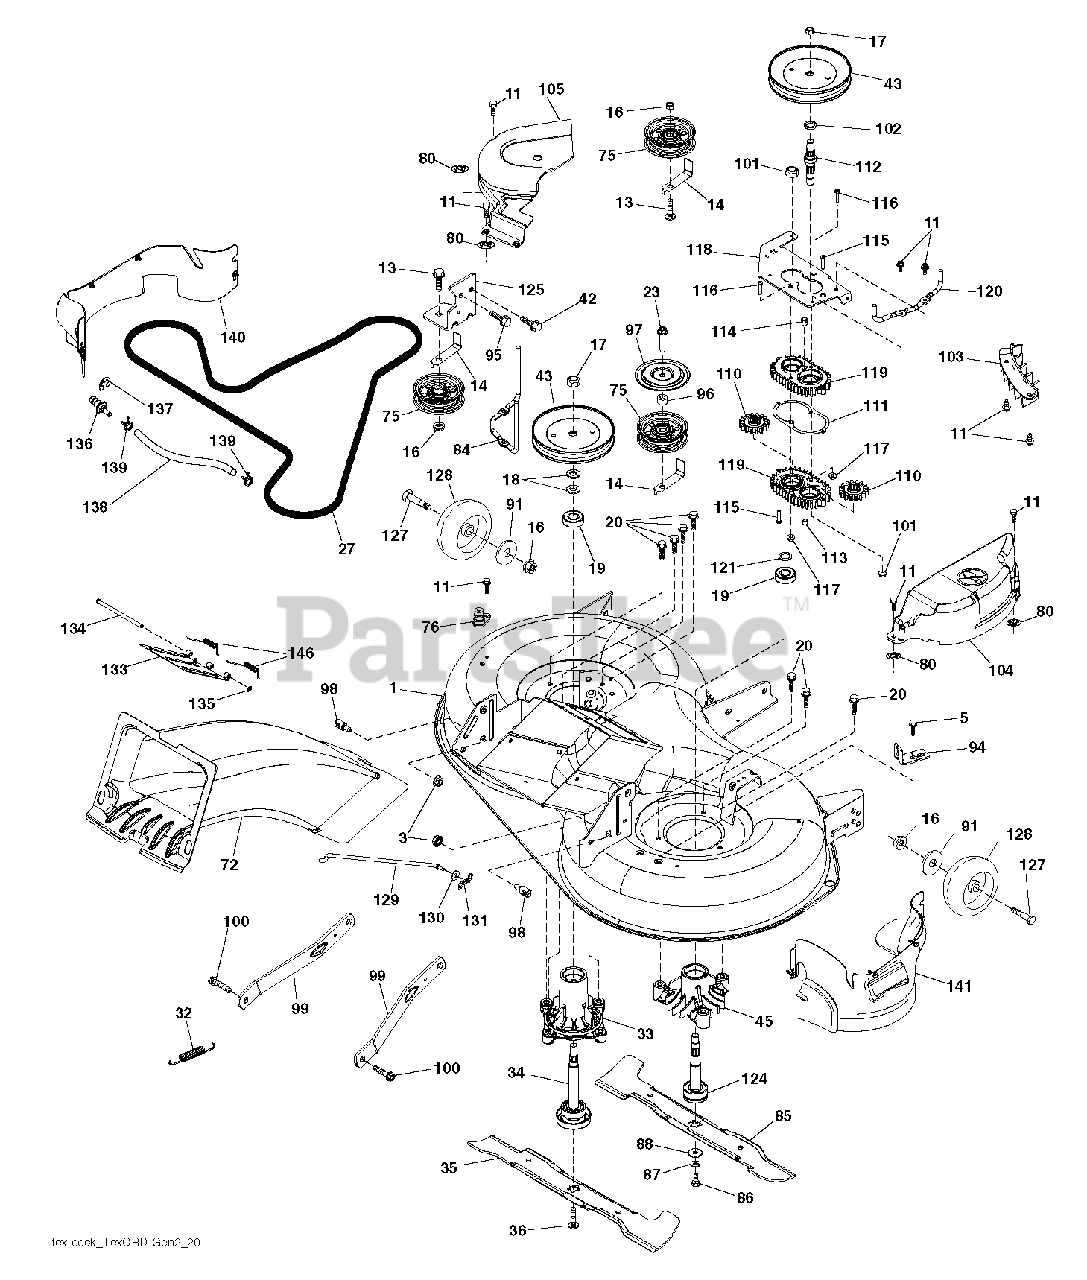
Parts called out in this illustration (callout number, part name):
3	NUT LOCK HEX FLANGE 5/16-18
5	BOLT.5/16HEX.WHS.HD
11	SCREW.1/4-20X5/8
13	BOLT.3/8-16X1.50
14	KEEPER, BELT IDLER
16	NUT LOCK FLG 3/8-16 UNC
17	NUT.FLANGE.LOCK.TOP
18	WASHER.SPACER.MANDREL
20	SCREW, WASHER HEAD
23	SCREW LT
27	BELT 97CM ELECTRIC
32	SPRING 107CM & 97CM ELECTRIC D
33	HOUSING.MANDREL.4PT.
34	SHAFT.ASM.MDRL.N/GREASE.38
35	BLADE.3N1.LH.CRD.97
36	BOLT.WASHER.ASM.7/16-2
42	SCREW
43	PULLEY.MANDREL.5.0.PD.38"
45	HOUSING.MANDREL.44/46" VENT
72	CHUTE.107/97.TEX.GEN2.TRIMMED
75	FLAT IDLER PULLEY
76	1/2" BARB.DECK.WASHOUT.PORT
80	PALNUT 1/4
84	BELT KEEPER.MANDREL.38"COATED
85	BLADE.3N1.RH.CRD.97
86	BOLT.3/8-24X1.25GR8. LHTHRD
87	LOCKWASHER
88	WASHER.BLADE
91	WASHER
94	BRKT.CLUTCH.CABLE
95	SCREW, 3/8-16X3/4
96	SPACER
97	PROTECTOR
98	STUD.FASTNER.W/ANTI-ROTATE
99	ARM.SUSPENSION.MOWER.R
100	BOLT.SHOULDER
101	NUT.CROWNLOCK.9/16 -18.UNC
102	SPACER BEARING
103	GUARD GUARD FRONT VENT
110	GEAR GEAR OUTPUT
111	GASKET GASKET GEARCASE
112	SHAFT SHAFT. CRD GEARCASE ADAP
113	PLUG PLUG OIL
114	VALVE VALVE RELIEF
115	SCREW
116	BOLT.CARIGE.SS.1/4-20X1.75GR5
117	NUT T
118	ARM ARM CLUTCHING
119	GEARCASE GEARCASE SUBASM
120	BRACKET KEEPER BELT RH
121	WASHER WASHER
124	MANDREL SHAFT NON/GREASE
125	BRACKET BRACKET IDLER CHASSES
127	BOLT.SHOULDER.3/8-16X3-5/8.
128	WHEEL. GUAGE RALLY
129	ROD ROD. SWAY CRD GEN II
130	WASHER
131	PIN.COTTER.5/16.BOW TI
133	DOOR
134	PIN PIN.HINGE
135	E-RING.5/16"
136	PLUG WASHOUT PORT HOOKUP
138	HOSE.3/8ID.BULK.12"
139	HOSE.3/8.CLAMP (2 2)
140	GUARD
141	GUARD SUBASM.TEX CRD 97CM RH F
146	SPRING SPRING: EZ MULCH DOOR
